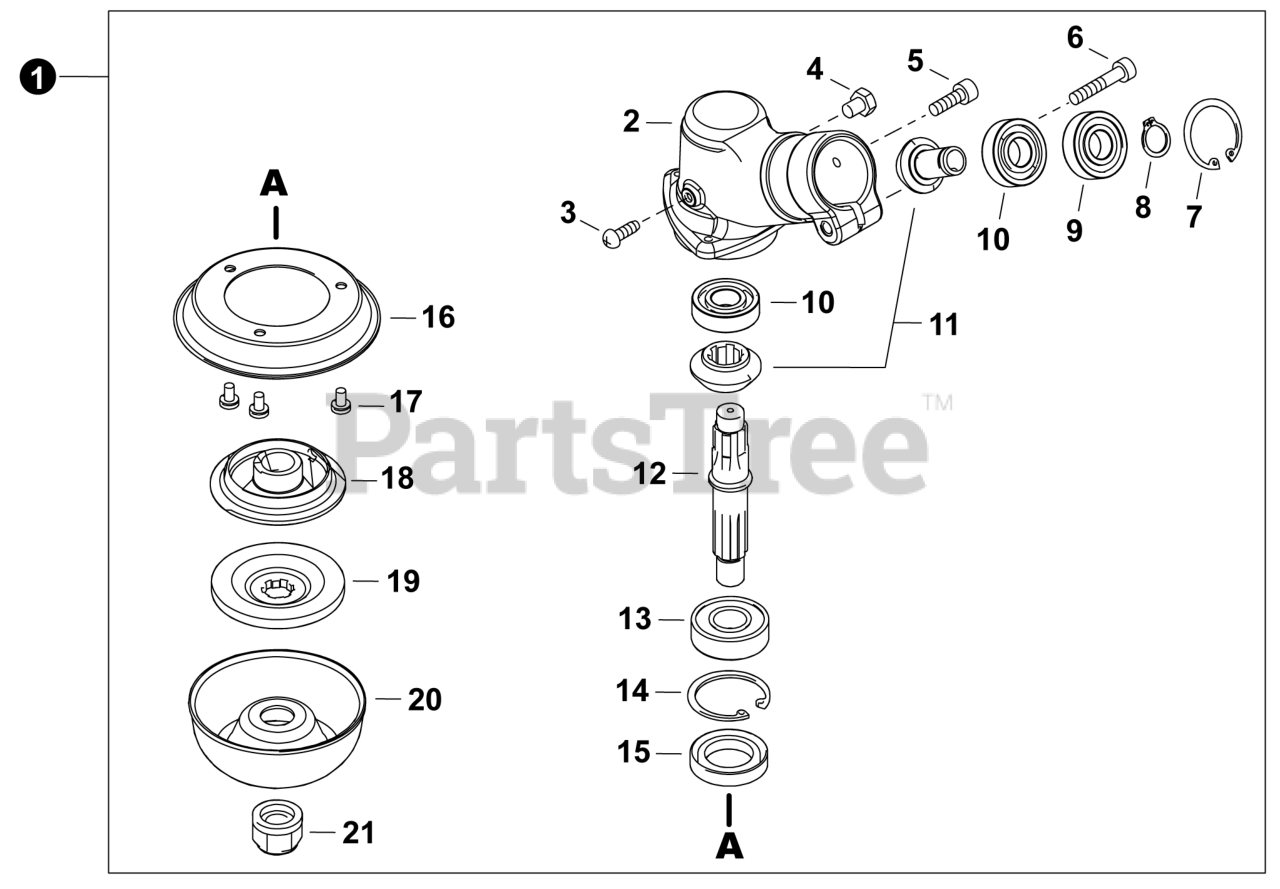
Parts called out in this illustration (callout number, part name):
1	GEAR CASE ASSY
2	CASE, GEAR
3	BOLT 4x10
4	BOLT 6x8
5	BOLT 5x14
6	BOLT 6x30
7	RING, SNAP 28
8	RING, SNAP 12
9	BEARING, BALL 6001Z
10	BEARING, BALL 6001
11	GEAR SET, BEVEL
12	SHAFT, GEAR
13	BEARING, BALL
14	RING, SNAP 35
15	SEAL, OIL
16	COVER, GEAR CASE
17	BOLT 4x8
18	PLATE, ADAPTER - UPPER
19	PLATE, ADAPTOR - LOWER
20	ADAPTER, SAW
